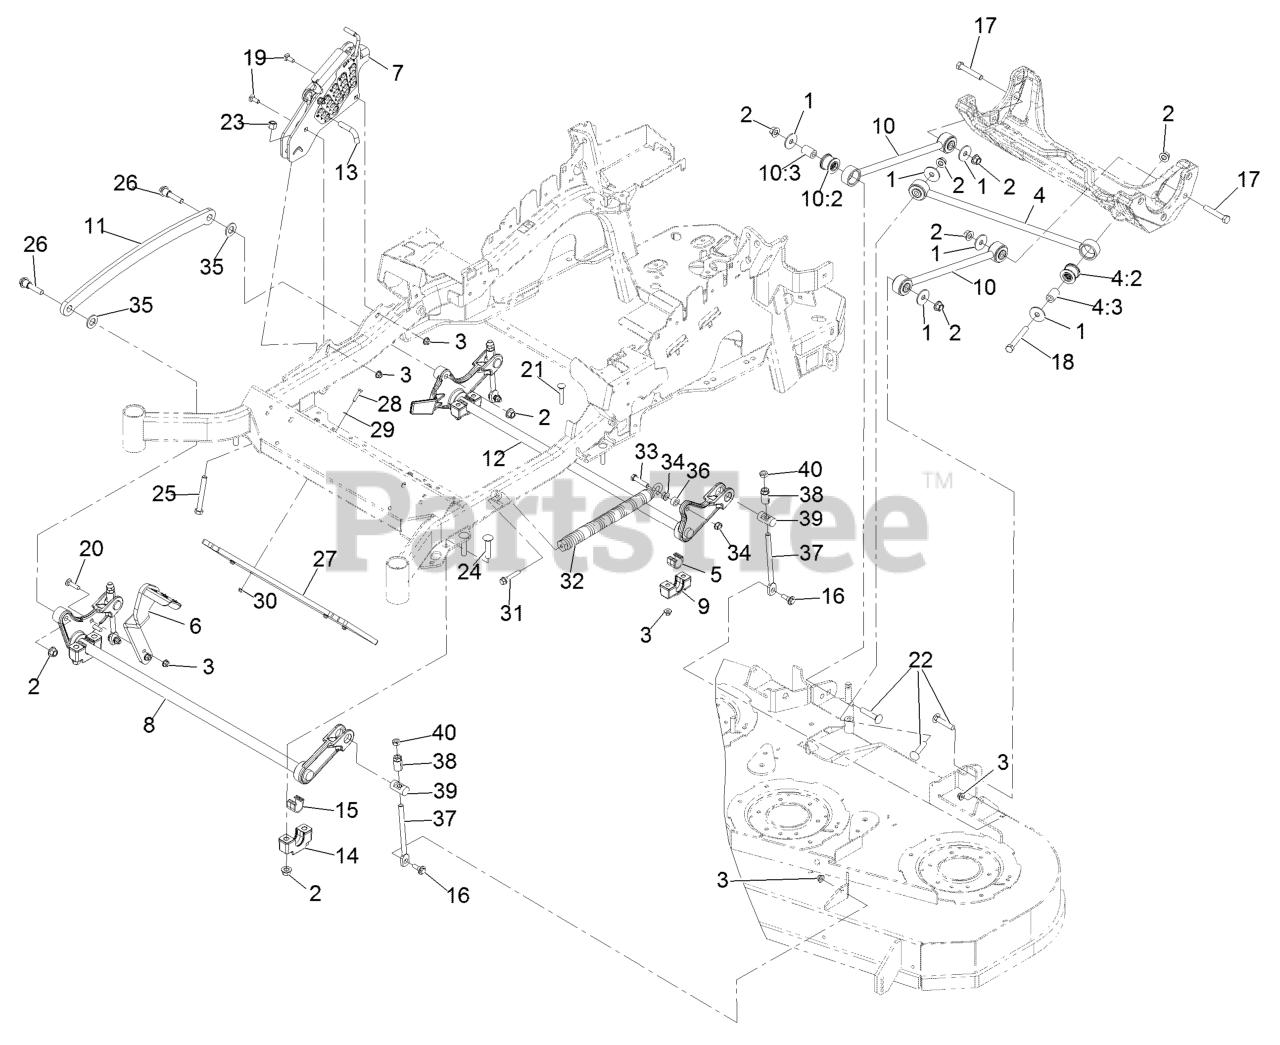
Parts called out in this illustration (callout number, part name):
1	WASHER-THRUST
2	Nut-Lock 1/2-13
3	NUT-HF, NI
4	PANHARD ROD ASM
4:2	BUSHING-SUSPENSION, RUBBER
5	BEARING-CROSS SHAFT, REAR
6	LEVER-FOOT
7	HOC ASM
8	DECKLIFT-FRONT
9	SUPPORT-CROSS SHAFT, BEARING REAR
10	DECK STRUT ASM
10:2	BUSHING-SUSPENSION, RUBBER
11	LINK-LIFT, DECK
12	LIFT-DECK, REAR
13	PIN-HOC
14	SUPPORT-CROSS SHAFT, BEARING
15	BEARING-CROSS SHAFT, FRON
16	SCREW-SHOULDER, HHF
17	SCREW-HH
18	SCREW-HH
19	BOLT-CARR
20	SCREW-CARR
21	Bolt-Carriage 3/8-16 X 2 1/4
22	SCREW-CARR
23	NUT-LOCK, NI
24	Bolt-Carriage 1/2-13 X 2 1/2 Spl Neck
25	BOLT-TAP
26	SCREW-HHF, SHOULDER
27	WEIGHT-TOE BOARD
28	SCREW-HH
29	WASHER-FLAT
31	BOLT-SHOULDER
32	SPRING-EXTENSION
33	SCREW-HH
35	WASHER-FLAT
37	LINK-ADJUSTER, DECK LIFT
38	ADJUSTER-LIFT, DECK
39	TRUNNION
40	NUT-JAM
